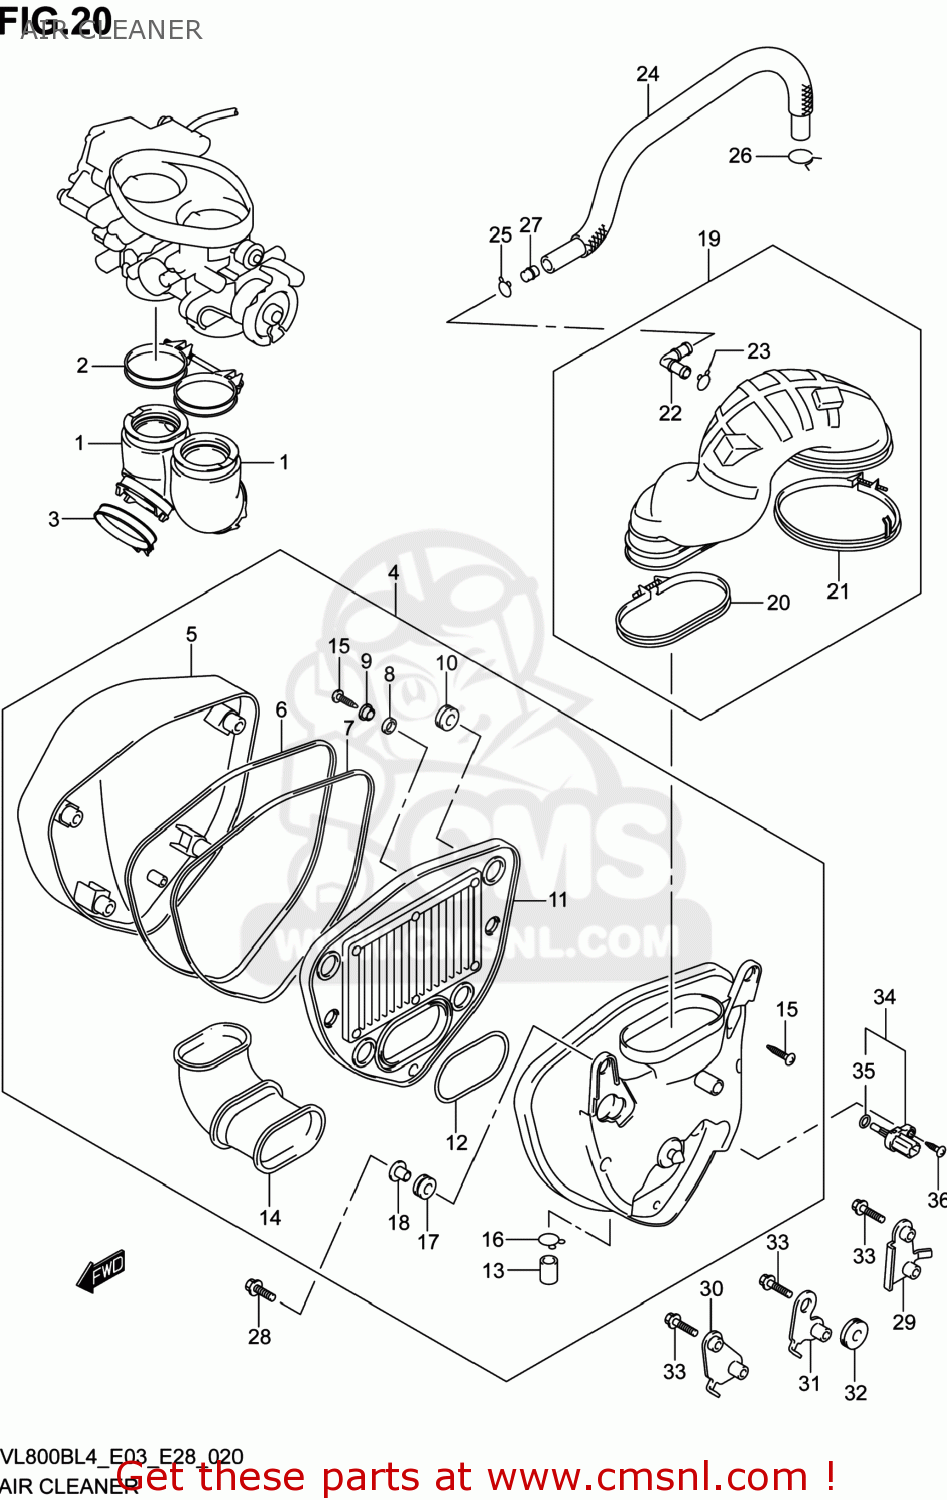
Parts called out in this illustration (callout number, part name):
1	PIPE,INTAKE
2	CLAMP,INTAKE PIPE
3	CLAMP,INTAKE PIPE
4	CASE ASSY,AIR CLEANER
5	CAP,AIR CLEANER
6	GASKET (NAS)
7	GASKET (NAS)
8	CUSHION
9	WASHER
10	CUSHION
11	FILTER,AIR CLEANER
12	GASKET,FILTER (NAS)
13	PLUG
14	TUBE,INLET
15	SCREW
16	CLIP
17	CUSHION
18	COLLAR,CLEANER CASE
19	TUBE ASSY,OUTLET
20	CLAMP
21	CLAMP
22	JOINT
23	CLIP
24	TUBE,BREATHER
25	CLIP
26	CLAMP
27	JET,BREATHER
28	SCREW(6X20)
29	BRACKET,AIR CLEANER NO.1
30	BRACKET,AIR CLEANER NO.2
31	BRACKET,AIR CLEANER NO.3
32	CUSHION
33	BOLT
34	SENSOR,AIR TEMP
35	O RING
36	SCREW
